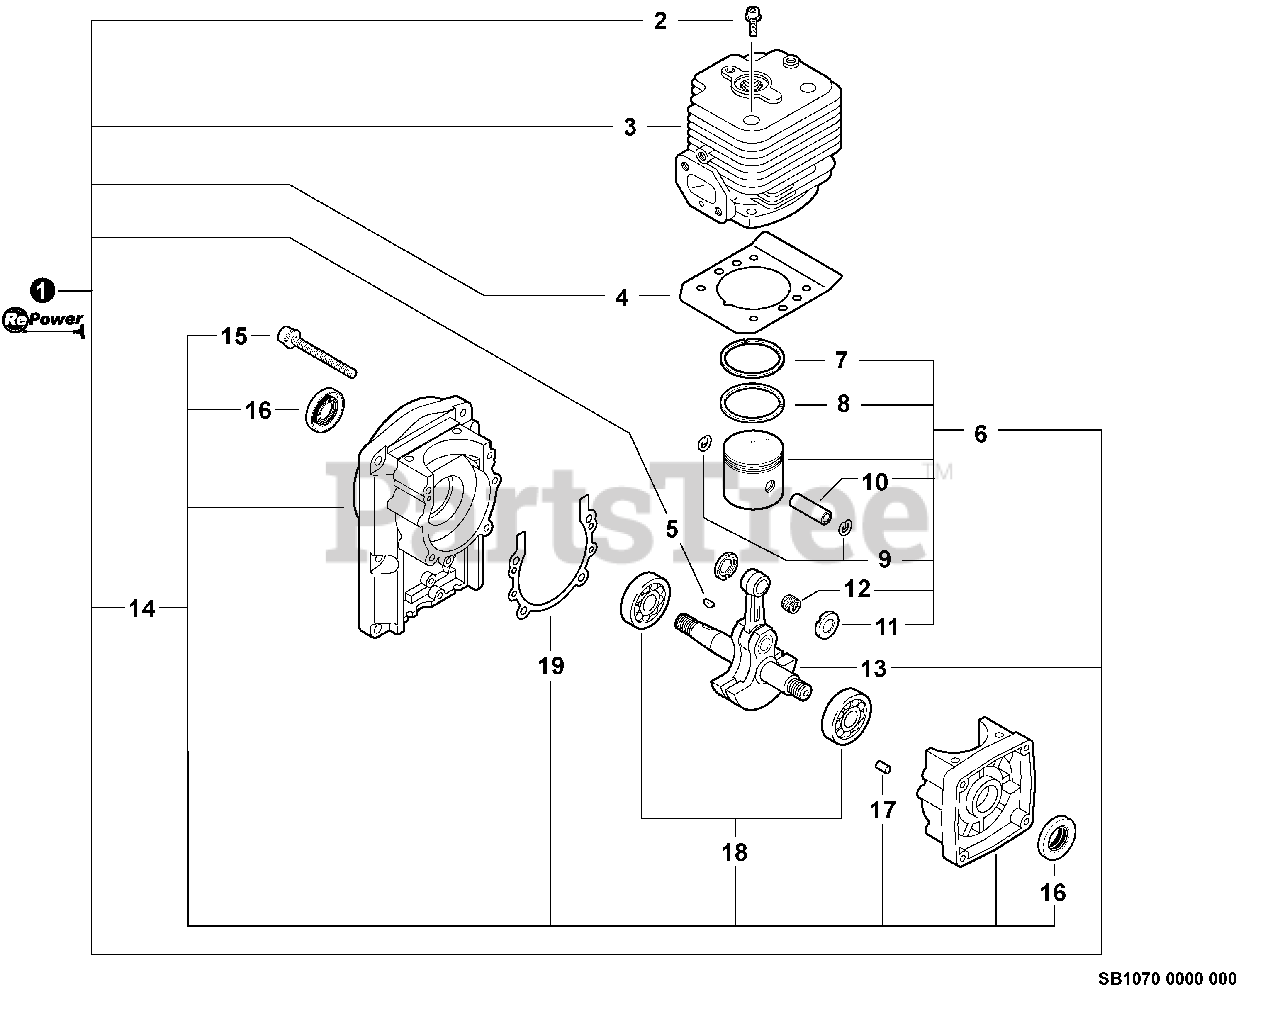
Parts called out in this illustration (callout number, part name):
1	SHORT BLOCK -- SB1070
2	SCREW - 5X25
3	CYLINDER
4	GASKET, CYLINDER
5	KEY - 3X14
6	PISTON KIT
7	RING, PISTON
8	RING, PISTON
9	RING, RETAINING - 8
10	PIN, PISTON
11	WASHER - 10
12	BEARING, NEEDLE - 10
13	CRANKSHAFT ASSY
14	CRANKCASE KIT
15	SCREW - 5X35
16	SEAL, OIL
17	PIN - LOCATING
18	BEARING, BALL - 6302
19	GASKET, CRANKCASE
